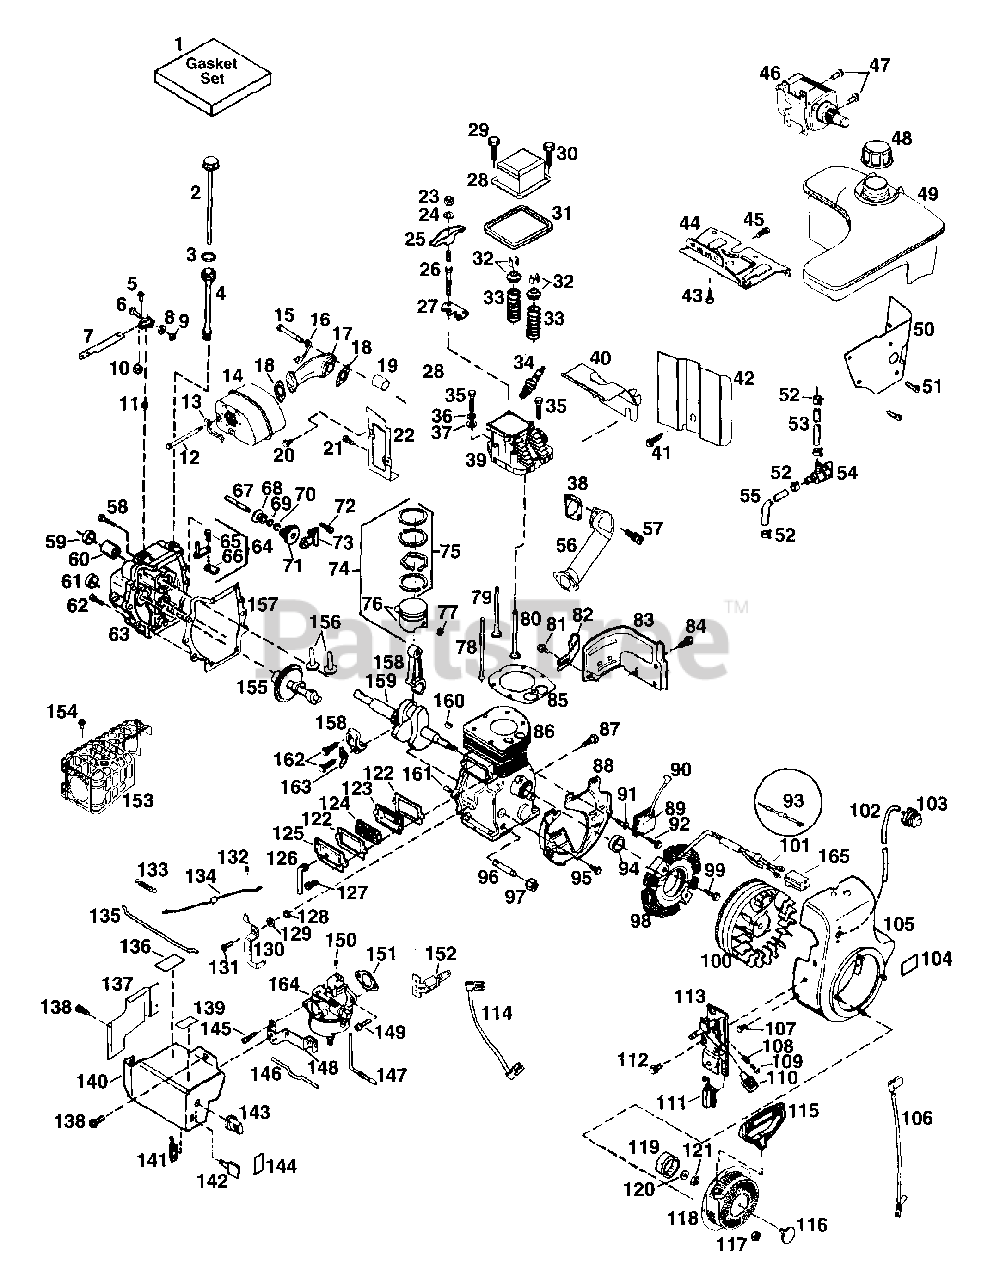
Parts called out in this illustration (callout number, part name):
1	Gasket Set
4	Oil Fill Tube
5	Screw, Torx T-15, 8-32 x 3/8"
6	Screw, 10-32 x 3/4"
7	Governor Lever
8	Lock Washer
9	Lock Nut, 10-32
10	Lock Nut, 10-32
11	Retaining Ring
12	Screw, 5/16-18 x 4-1/2"
13	Locking Plate
15	Screw, 5/16-18 x 1-9/32"
16	Locking Plate
17	Exhaust Manifold
18	Exhaust Gasket
19	Exhaust Port Liner
20	Screw, 1/4-20 x 5/8"
21	Lock Nut, 10-32
22	Blower Housing Extension
24	Lock Washer
25	Rocker Arm
26	Rocker Arm Stud
27	Push Rod Guide
28	Rocker Arm Cover
29	Valve Cover Mounting Stud
30	Screw, Torx T-30, 1/4-20 x 1/2"
31	Rocker Arm Cover Gasket
32	Valve Spring Keeper
33	Valve Spring
34	Spark Plug (RN4C)
35	Screw, 5/16-18 x 2-1/2"
36	Belleville Washer
38	Intake Pipe Gasket
39	Cylinder Head
40	Cylinder Head Cover
41	Screw, 10-32 x 1/2"
42	Heat Baffle
43	Screw, 1/4-15 x 3/4"
44	Fuel Tank Bracket
45	Screw, 5/16-18 x 7/8"
46	Electric Starter Motor (110 Volt)
47	Screw, Torx T-30, 1/4-20 x 15/32"
48	Fuel Cap
49	Fuel Tank
50	Fuel Tank Extension
51	Screw, 10-32 x 1/2"
52	Fuel Line Clamp
53	Fuel Line
54	Fuel Shut-Off Valve
55	Fuel Line
56	Intake Pipe
57	Screw, Torx T-30, 5/16-18 x 7/8"
58	Screw, 1/4-20 x 1-3/16"
60	Crankshaft Bushing
61	Camshaft Seal
62	Screw, 1/4-20 x 1-11/16"
63	Cylinder Cover
64	Governor Rod Ass'y
65	Screw, 6-40 x 5/16"
66	Governor Yoke
67	Governor Shaft
68	Governor Spool
70	Retaining Ring
71	Governor Gear Ass'y
72	Screw, 10-24 x 1/2"
73	Governor Gear Bracket
74	Piston, Pin & Ring Set (Std.)
75	Ring Set (Std.)
76	Piston & Pin Ass'y (Std.)
77	Piston Pin Retaining Ring
79	Exhaust Valve (Std.)
80	Intake Valve (Std.)
81	Screw, 10-24 x 3/16"
82	Fill Tube Clip
83	Blower Housing Extension
84	Screw, Torx T-30, 1/4-20 x 1/2"
85	Cylinder Head Gasket
86	Cylinder
87	Screw, 1/4-20 x 1/2"
88	Blower Housing Baffle
89	Solid State Ignition
90	Spark Plug Cover
91	Solid State Mounting Stud
92	Screw, Torx T-15, 10-24 x 15/16"
95	Screw, 1 /4-20 x 5/8"
96	Oil Drain Extension
97	Extension Cap
98	Alternator Coil (3/5)
99	Screw, 1 /4-20 x 3/4"
100	Flywheel (W/Ring Gear)
102	Primer Line
103	Primer Ass'y
104	Primer Decal
105	Blower Housing
106	Ground Wire
107	Screw, Torx T-40, 5/16-24 x 21/32"
108	Compression Spring
109	Screw, Torx T-10, 5-40 x 7/16"
110	Control Knob
112	Screw, 10-32 x 1/2"
113	Control Bracket
114	Ground Wire
115	Starter Handle
116	Starter Decal
117	Nut & Lock Washer, 1/4-28
118	Rewind Starter
119	Starter Cup
120	Lock Washer
121	Flywheel Nut
122	Valve Cover Gasket
123	Breather Body
124	Breather Element
125	Valve Cover
126	Breather Tube
127	Screw, 10-24 x 1/2"
130	Bellcrank Lever
131	Screw, 10-24 x 29/32"
133	Extension Spring
134	Governor Link
135	Throttle Link
136	Warning Decal
137	Carburetor Cover
138	Screw, 10-32 x 1/2"
139	Caution Decal
140	Carburetor Cover (Front)
142	Key Switch
143	Choke Knob
144	Choke Decal
145	Screw, 10-32 x 1/2"
146	Choke Spring
147	Choke Rod
148	Choke Bracket
149	Screw, 1/4-20 x 27/32"
151	Carburetor To Intake Pipe Gasket
152	Key Switch Bracket
153	Heat Shield
154	Screw, 10-32 x 5/16"
155	Camshaft (MCR)
156	Valve Lifter
157	Cylinder Cover Gasket
158	Connecting Rod Ass'y
159	Crankshaft
160	Flywheel Key
161	Dowel Pin
162	Connecting Rod Bolt
163	Oil Dipper
164	Carburetor
